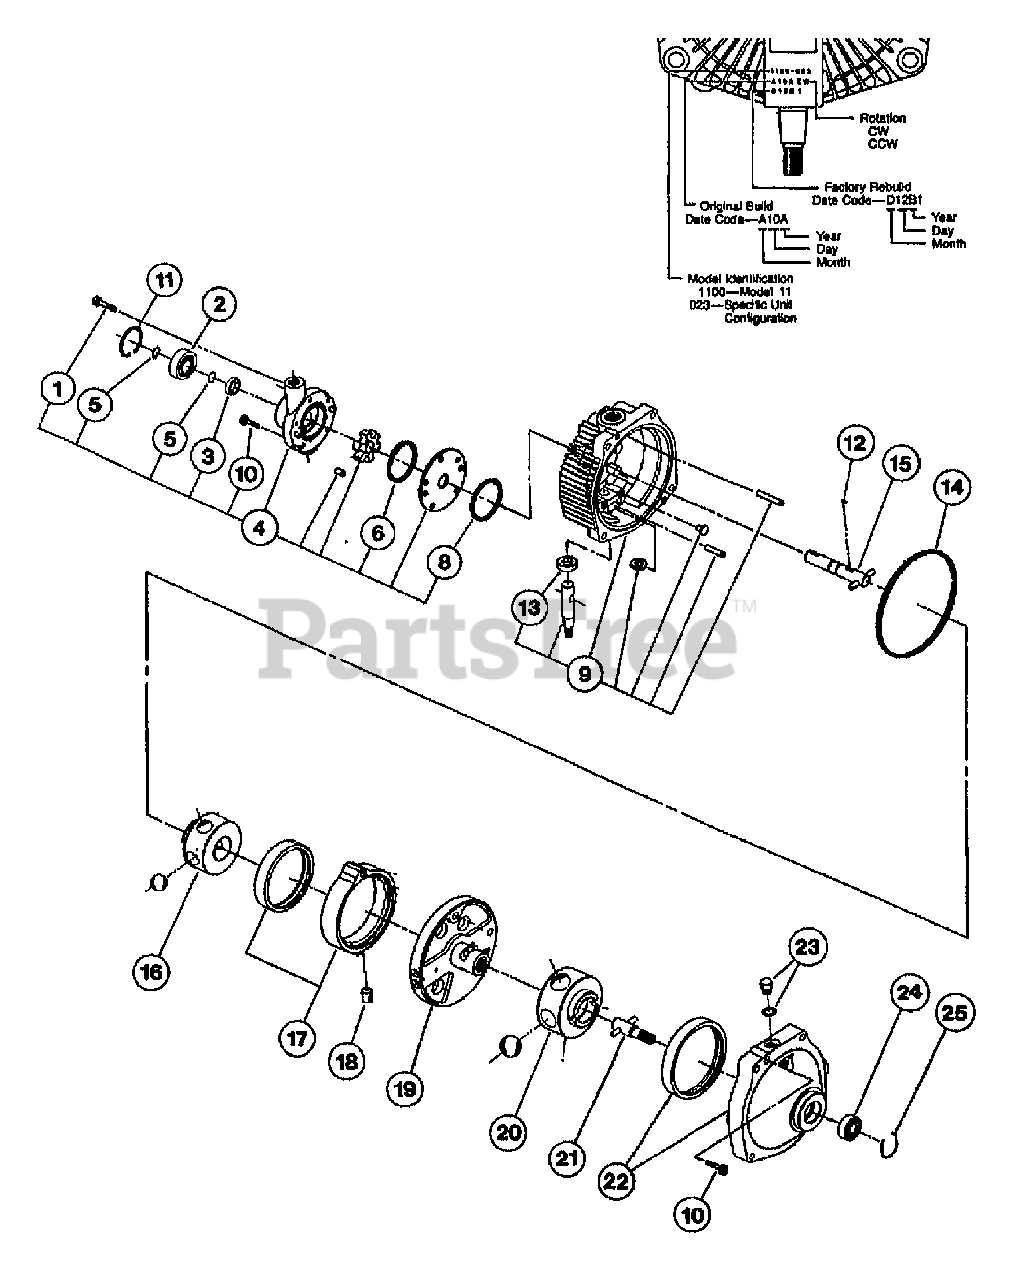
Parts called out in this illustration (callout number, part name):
1	SOCKET HD. CAPSCREW
3	SEAL-OIL
4	KIT-PUMP CHARGE
5	RING-SNAP
6	RING-SQ SEAL
8	RING-SQ SEAL
9	ASSM-COVER
10	SOCKET HD. CAPSCREW
12	PIN-DRIVE
13	SEAL-OIL
14	RING-SQ SEAL
15	SHAFT-INPUT (W/KEY)
16	ASSM-PUMP ROTOR & BALL
17	ASSM-RING CAM
18	RING-CAM INSERT
19	ASSM-PINTLE
20	ASSM-MOTOR ROTOR & BALL
21	SUBASSM-OUTPUT SHAFT
22	ASSM-BODY
23	SUBASSM-O RING PLUG
24	BRG-BALL (OUTPUT)
25	RING-RETAIN
